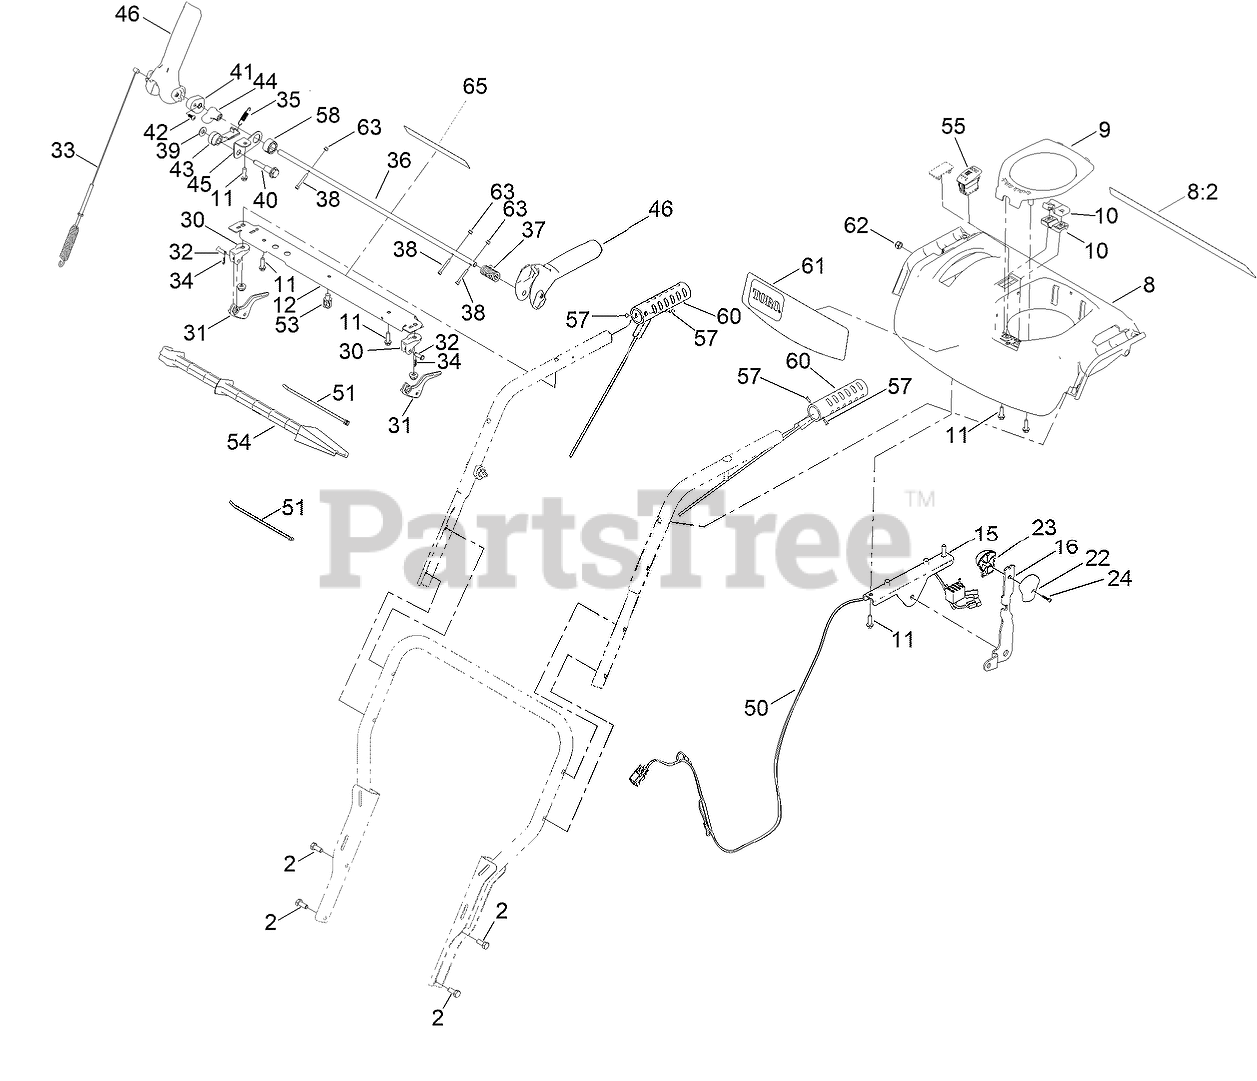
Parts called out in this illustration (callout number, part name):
2	SCREW-HH
8	PANEL-CONTROL, ASSEMBLY
8:2	DECAL-SAFETY
9	COVER-QUICKSTICK
10	SUPPORT-ROD
11	SCREW-PLASTITE, HWH
12	BRACE-CONSOLE
15	BRACKET-SHIFT
16	SELECTOR-SPEED
22	KNOB-SHIFT, LH
23	KNOB-SHIFT, RH
24	SCREW-PPH
30	MOUNT-LEVER, CLUTCH
31	LEVER-CLUTCH
32	PIN-CLEVIS
33	CABLE-AUGER
34	PIN-HAIR
35	SPRING-LOCKOUT, HANDLE
36	ROD-LOCKOUT
37	SPRING-TORSION, HANDLE RETURN
38	SCREW-HSH,SPL
39	WASHER-FLAT
40	SCREW-SHOULDER
41	HANDLE LOCK
42	SCREW-PPH
43	LATCH, LOCKOUT
44	CAM-LOCKOUT
45	LINK-LOCKOUT
46	LEVER-CONTROL
50	HARNESS-WIRE, LED AND HAND WARMERS
51	TIE-CABLE
53	CLIP-TIE
54	STICK-CLEANOUT
55	SWITCH-ROCKER, ON-NONE-OFF (HEATER)
57	RIVET-POP
58	COLLAR-CAM
60	RED HEATED GRIP
61	DECAL-CONSOLE
62	NUT-HEX
63	NUT-LOCK ROHS
65	DECAL-HYDRO
